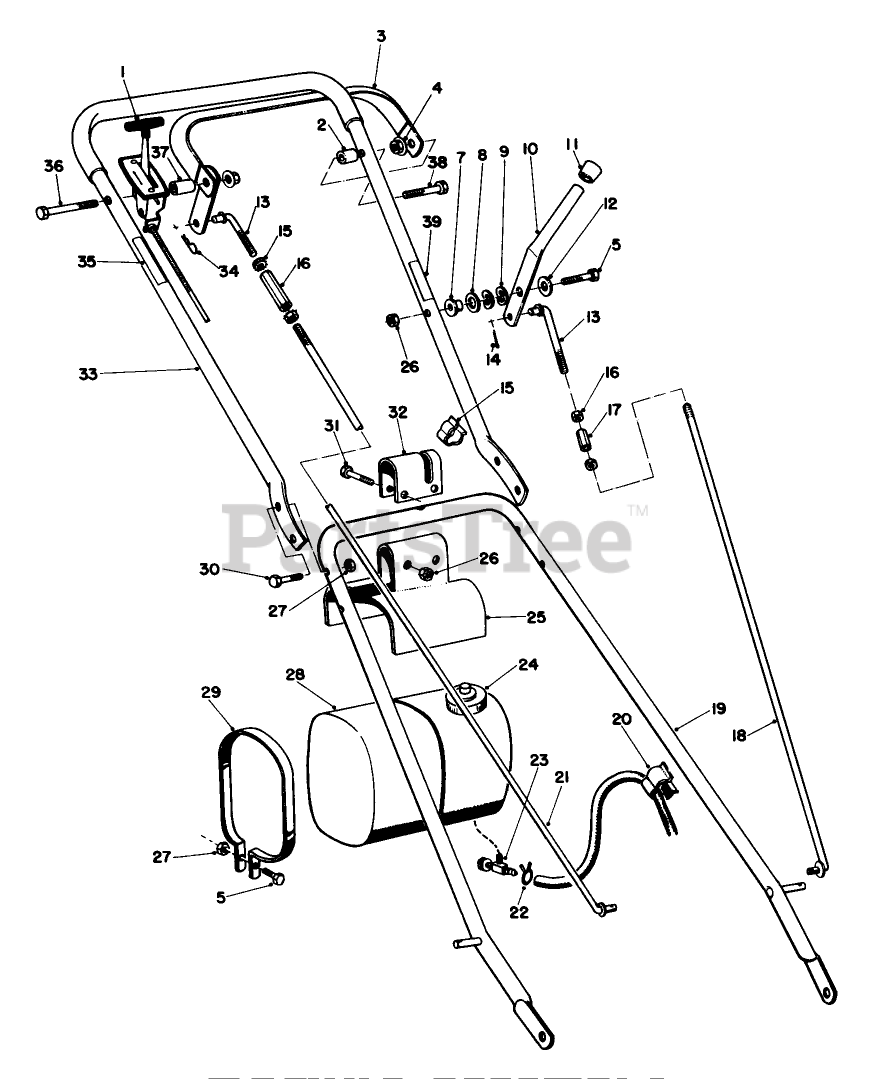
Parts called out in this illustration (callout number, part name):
2	SCREW-HHFTF
5	.503ID X .875LG BSHG
6	SEAT MTG WA
7	SHAFT-PIVOT, SEAT
8	DECAL-DANGER
10	RIVET-POP
11	DECAL-REFUELING
13	CLAMP-HOSE
15	NUT-HEX
16	CLAMP-MUFFLER
19	DECAL-INSTALLATION
20	AIR CLEANER ASM
21	NUT-SQUARE
22	SCREW
23	MOUNTING BAND ASM
24	SCREW-HH
26	NUT AND GASKET ASM
27	SKIRT-BAFFLE
28	CLAMP ASM
29	A/C CUP ASM
30	SCREW-HH
31	SCREW-HH
33	SCREW-HH
35	SCREW-HH
36	WASHER-LOCK
37	WASHER-FLAT
38	NUT-HEX
40	SPRING
41	PIN-SWITCH, SEAT
42	SCREW-HH
43	SCREW-HH
45	PIN-ROLL, SLOT
46	PIN-PEDAL
